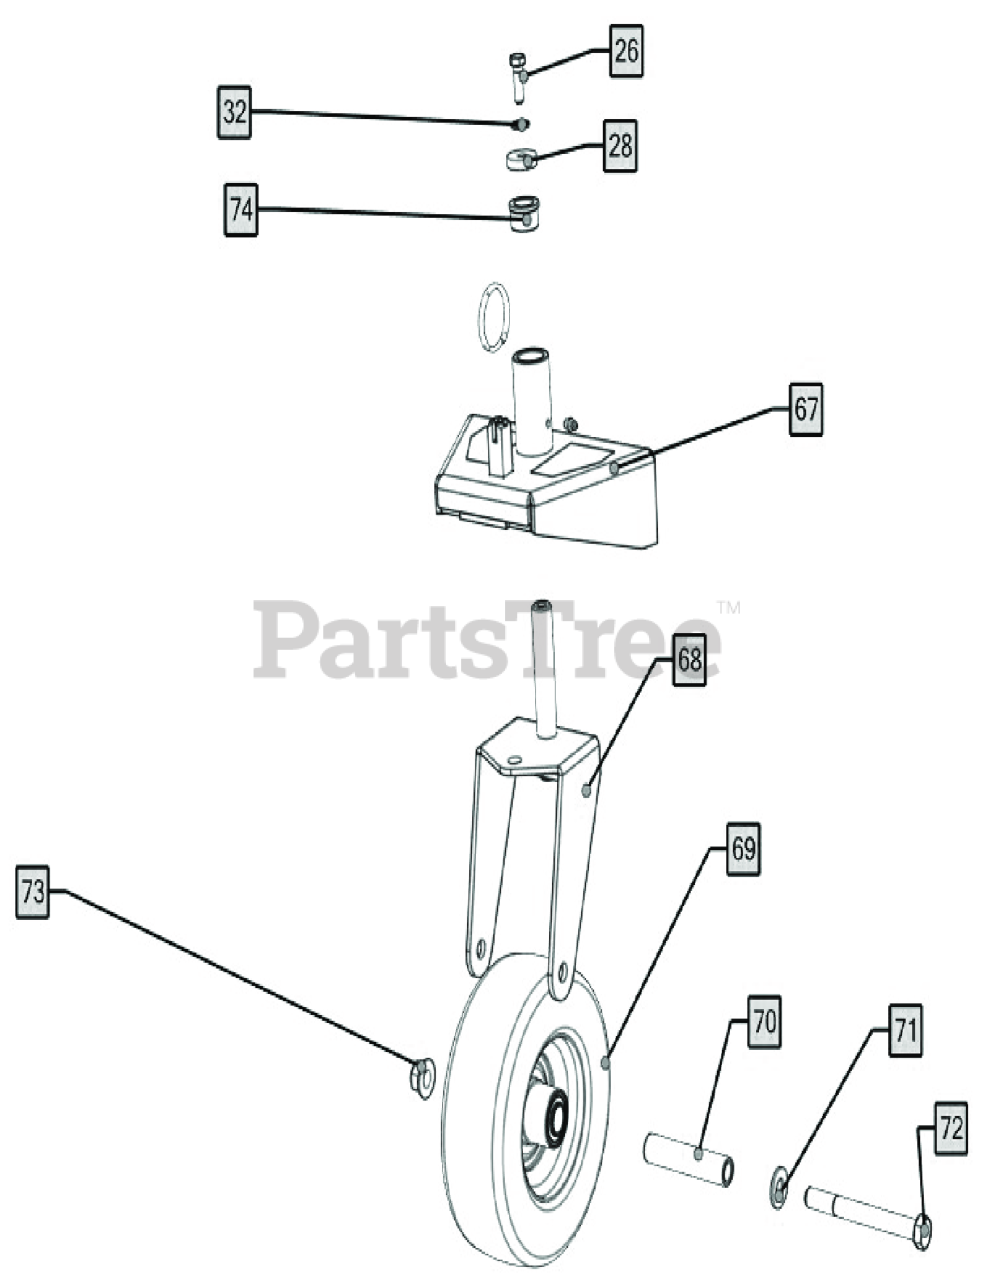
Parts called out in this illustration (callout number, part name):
26	SCREWCAP 5/16"-18 X 1" HCS ZP
28	WASHER 1.125 OD X 0.344 ID X .25 THK ZP
32	WASHER, BELLEVILLE CONTACT .323X.717X.05
67	SC181 GEARBOX SEAL KIT
68	BRACKET, CASTER 8"D X 3"W
69	WHEEL, 8" X 3" HEAVY DUTY
70	SPACER, .75 ID X 3.563 LG ZP
71	WASHER 1/2" SAE Z/P
72	SCREWCAP 1/2"-13 X 4 3/4 HCS ZP GR. 5
73	NUT-HEX-NYLK, FLG .500"-13 ZP
74	BUSHING FLANGE 1" OD 3/4" ID
